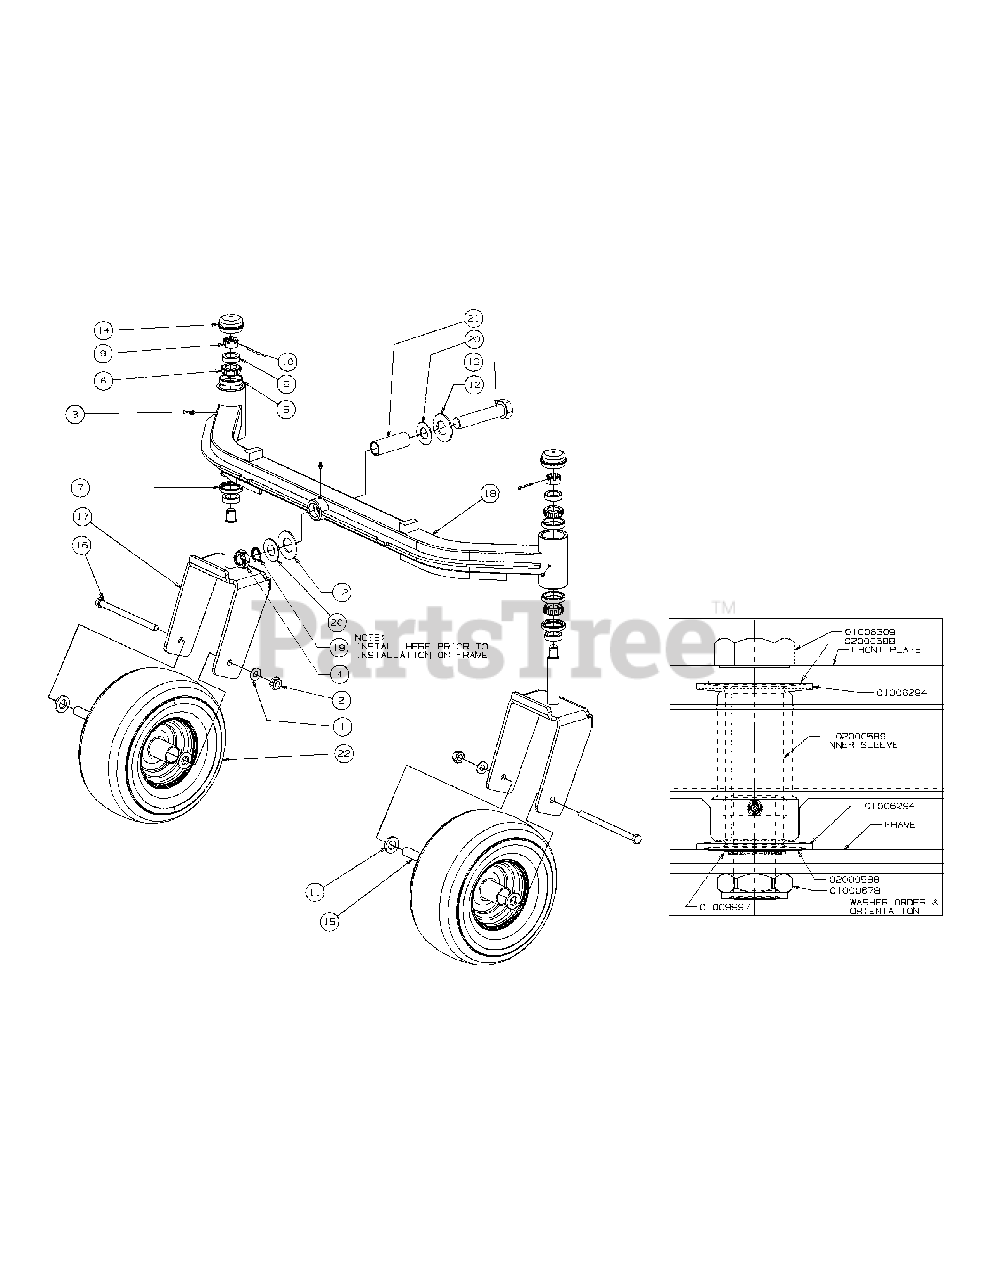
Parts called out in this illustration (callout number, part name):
1	Washer, 1/2 x 1 Shim
2	Nut, 1/2-20, Center Lock
3	Grease Fitting
4	Nut, Jam, 1.0-14, Insert Lock
5	Cup Bearing
6	Bearing Cone
7	Seal
8	Ring Seal
9	Slotted Nut, 3/4-16
10	Cotter Pin, 5/32, 1.25
11	Spacer, .812 ID x .218LG
12	Bell Washer, 1.25 ID x 2.5 OD x .180
13	Hex Cap Screw, 1-14 x 5.0
14	Grease Cap, 1.986 OD
15	Wheel Spacer
16	HHCS, 1/2-20, 7.50
17	Yoke, Caster Wheel
18	Front Axle Assembly
19	Retainer Extension, Self Locking
20	Flat Washer, 1.00 ID x 2.00 OD x .075
21	Spacer, 1.005 ID x 1.25 OD x 3.6
22	Wheel, 13 x 6.50 x 6.0, Beige, includes
22	Roller Bearings
22	Retainer Bushings
